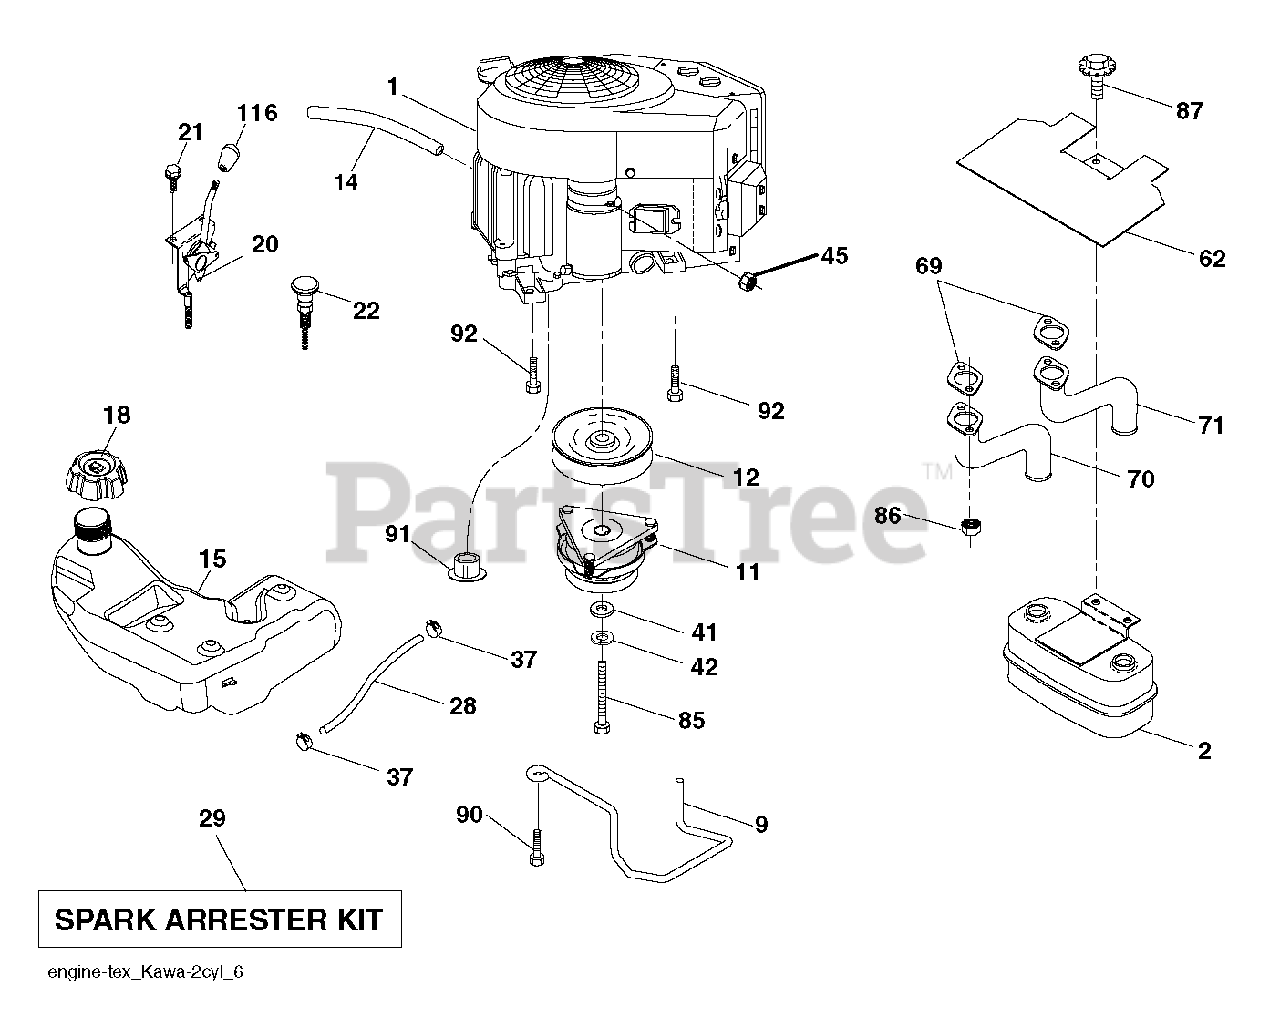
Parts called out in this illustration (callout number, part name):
2	MUFFLER ASSM
9	KEEPER.BELT.ENGINE.4.2
12	PULLEY ENGINE
14	TUBE, DRAIN OIL ASM.
15	TANK.ASM.4.GAL.EPA
18	CAP ASM.FL.RTCHT.3"GRY.E10
20	CONTROL THROTTLE
21	SCREW.#10 X 0.750.BOS THREAD
22	CONTROL CHOKE
28	LINE.FUEL.64"REAR.EMIS
29	ARRESTER SPARK (OPTIONAL)
37	HOSE CLAMP
42	LOCKWASHER
62	SHIELD.HEAT.MUFFLER
70	TUBE.EXHAUST
71	TUBE.EXHAUST
85	BOLT HEX 7/16-20 X 3.75 GR. 5
87	BOLT.5/16-18UNCX1.W/SE
90	SCREW 3/8-16X1
91	BUSHING.1.375OD
92	SCREW 3/8-16X1
116	RP KNOB SOFT TOUCH
